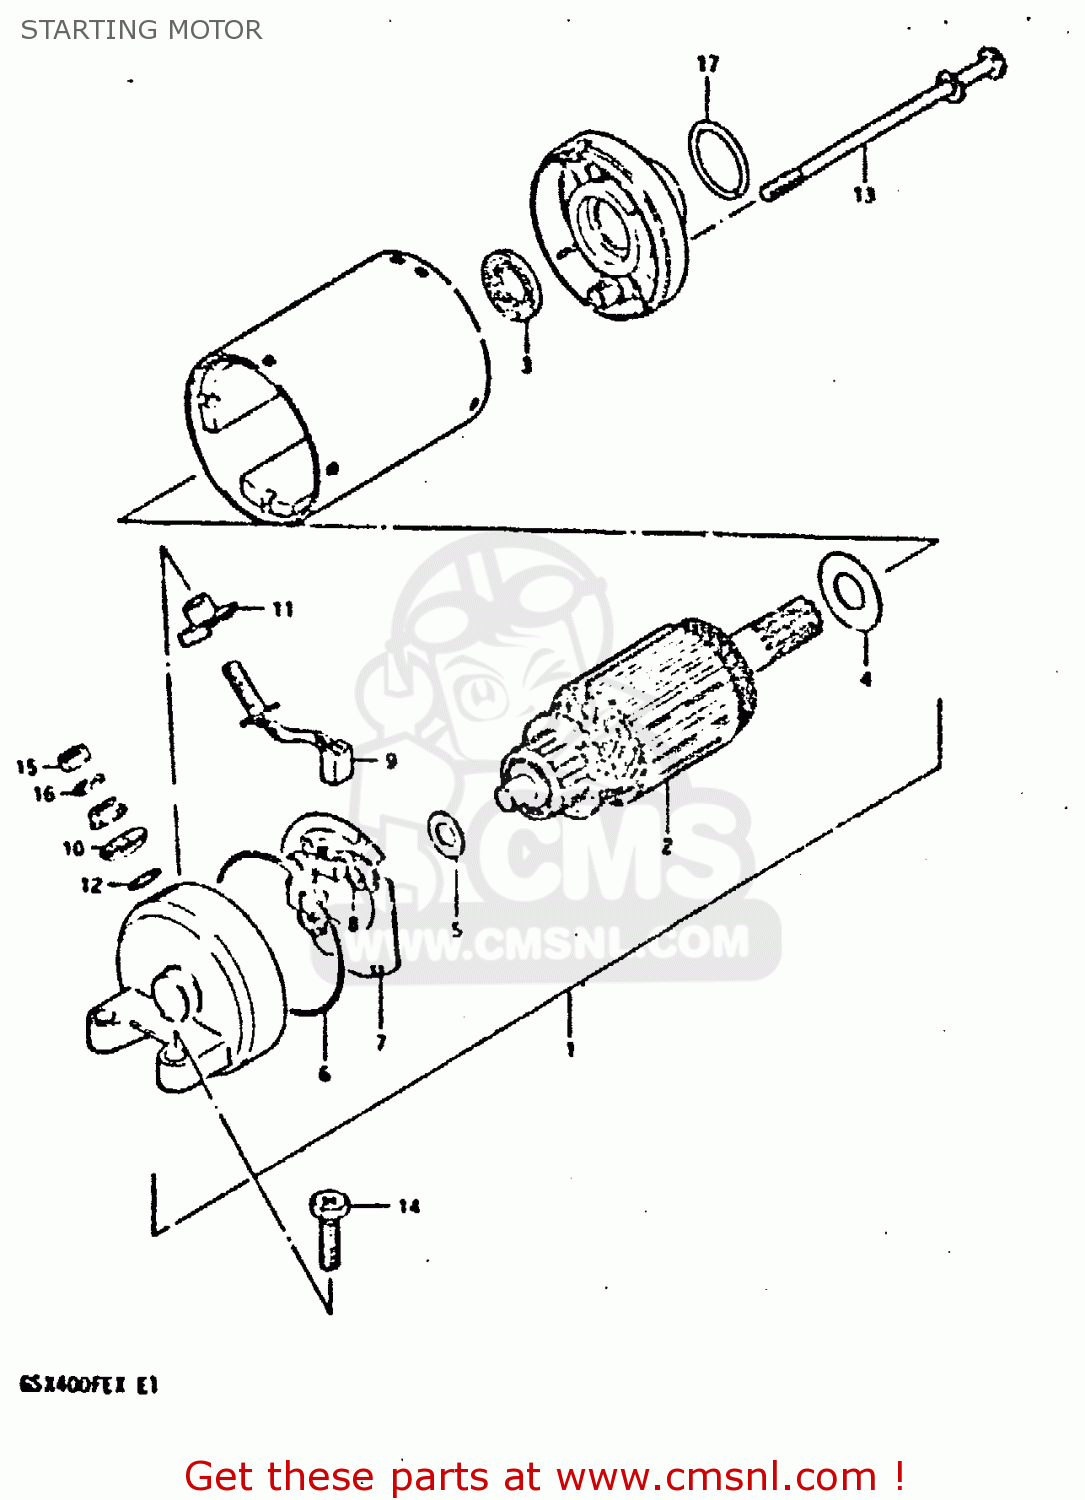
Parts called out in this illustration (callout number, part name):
1	MOTOR ASSY, STARTING
2	ARMATURE
3	SEAL,OIL
4	SHIM (A)
5	SHIM (B)
6	O RING
7	HOLDER,BRUSH
8	SPRING
9	BRUSH (+)
10	BUSHING (1)
11	BUSH,NO.2
12	O-RING
13	BOLT,STARTING MOTOR HOUSING
14	SCREW (6X25)
15	NUT 6MM
16	LOCK WASHER
17	O RING(D:2,ID:24.5)
